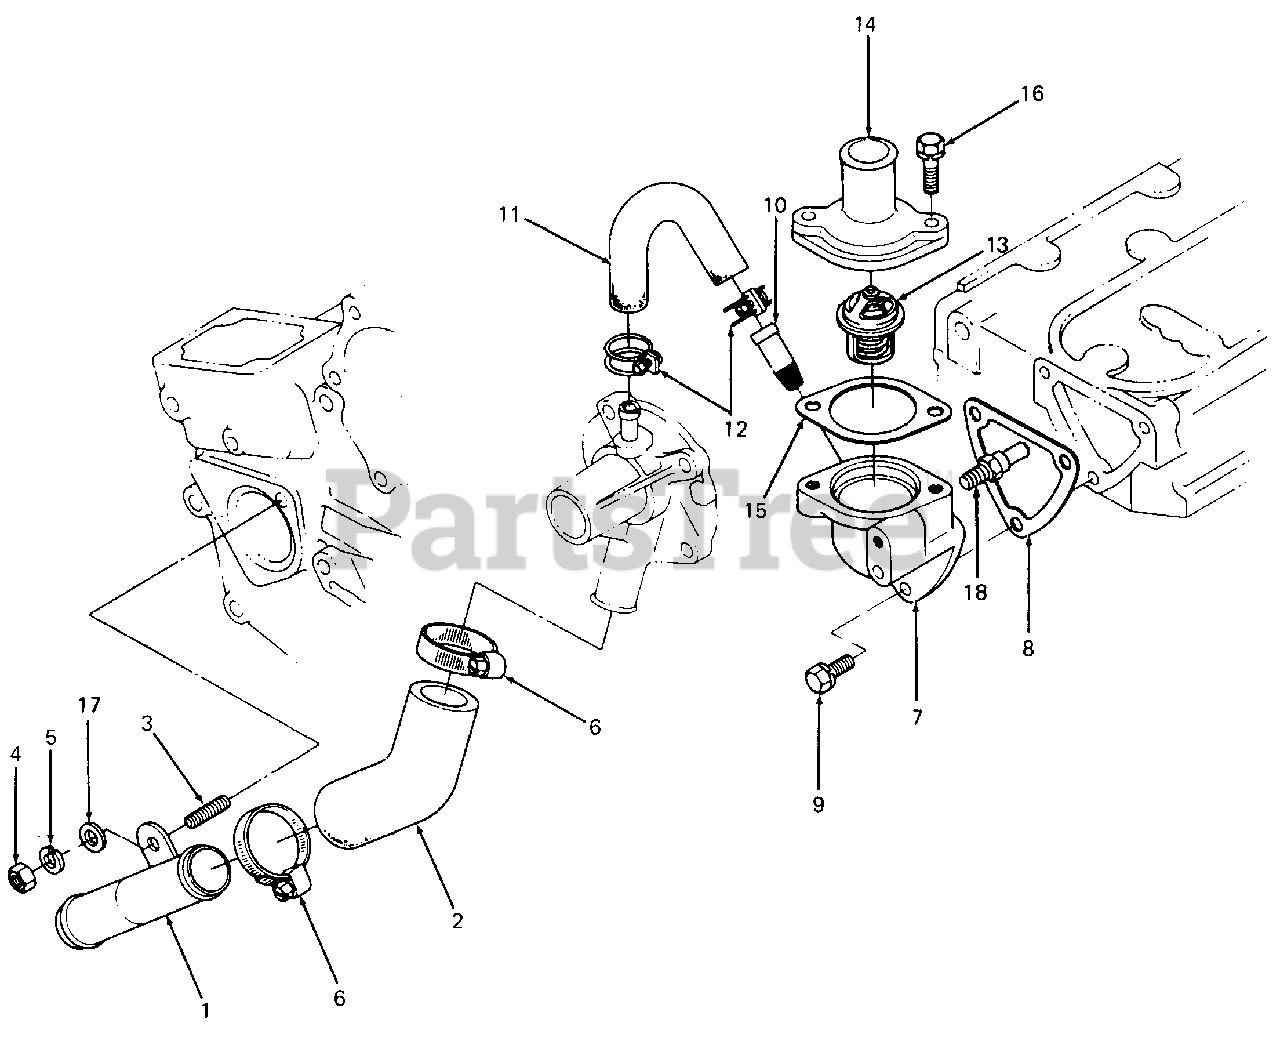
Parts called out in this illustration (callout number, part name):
5	Washer, Spring
7	Flange, Water
8	Gasket, Water Flange
9	Screw w/Washer
10	Pipe, Water Return
11	Pipe, Water Return
13	Thermostat
14	Cover, Thermostat
15	Gasket, Thermostat Cover
16	Screw w/Washer
18	Thermoswitch Assy
